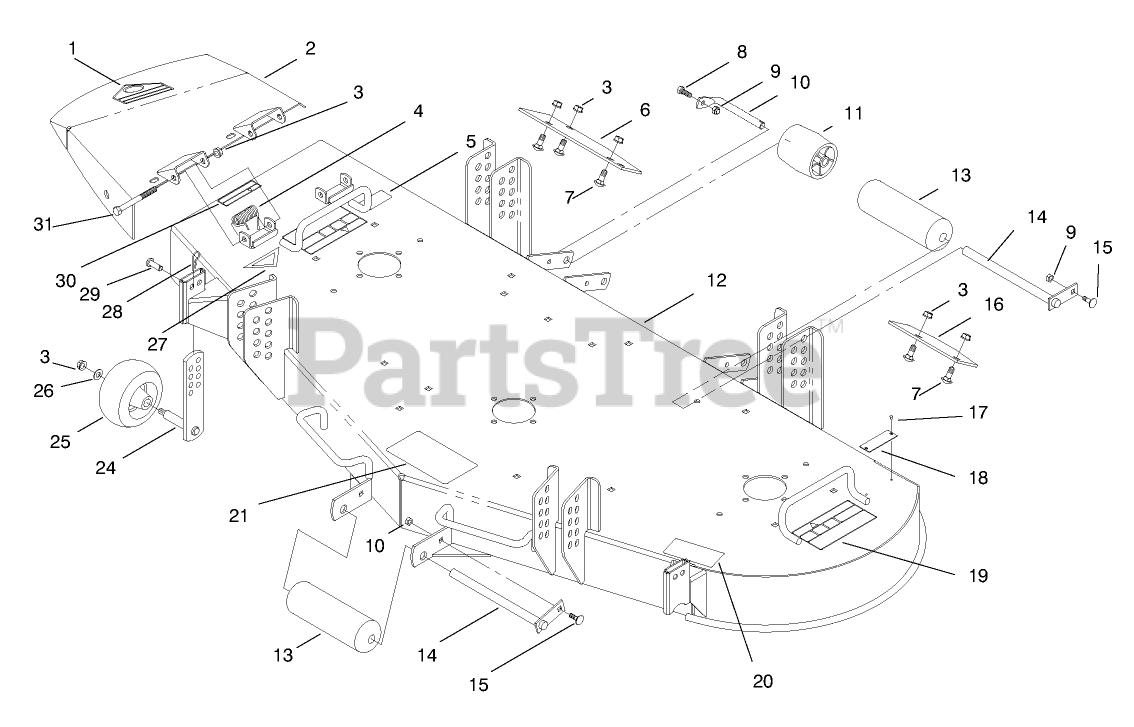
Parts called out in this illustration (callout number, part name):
1	DECAL-DANGER
2	Chute-ASM
2	CHUTE ASM
3	NUT-LOCK, NI
4	SPRING
6	PLATE-WEAR, RH
7	BOLT-CARR
8	SCREW-HH
9	NUT-LOCK, NI
10	ROLLER-SHAFT
11	Roller
12	ASM - 60" DECK W/DECALS
13	ROLLER-ANTI SCALP
14	ROLLER-SHAFT
15	BOLT-CARR
16	PLATE-WEAR, LH
19	DECAL-DANGER, THROWN OBJECT
20	DECAL - WHEEL ADJUSTMENT
24	GAGE-WHEEL
25	WHEEL-GAGE
26	WASHER-FLAT
28	PIN-HAIR
29	PIN-CLEVIS
30	DECAL-DANGER
31	SCREW-HH
